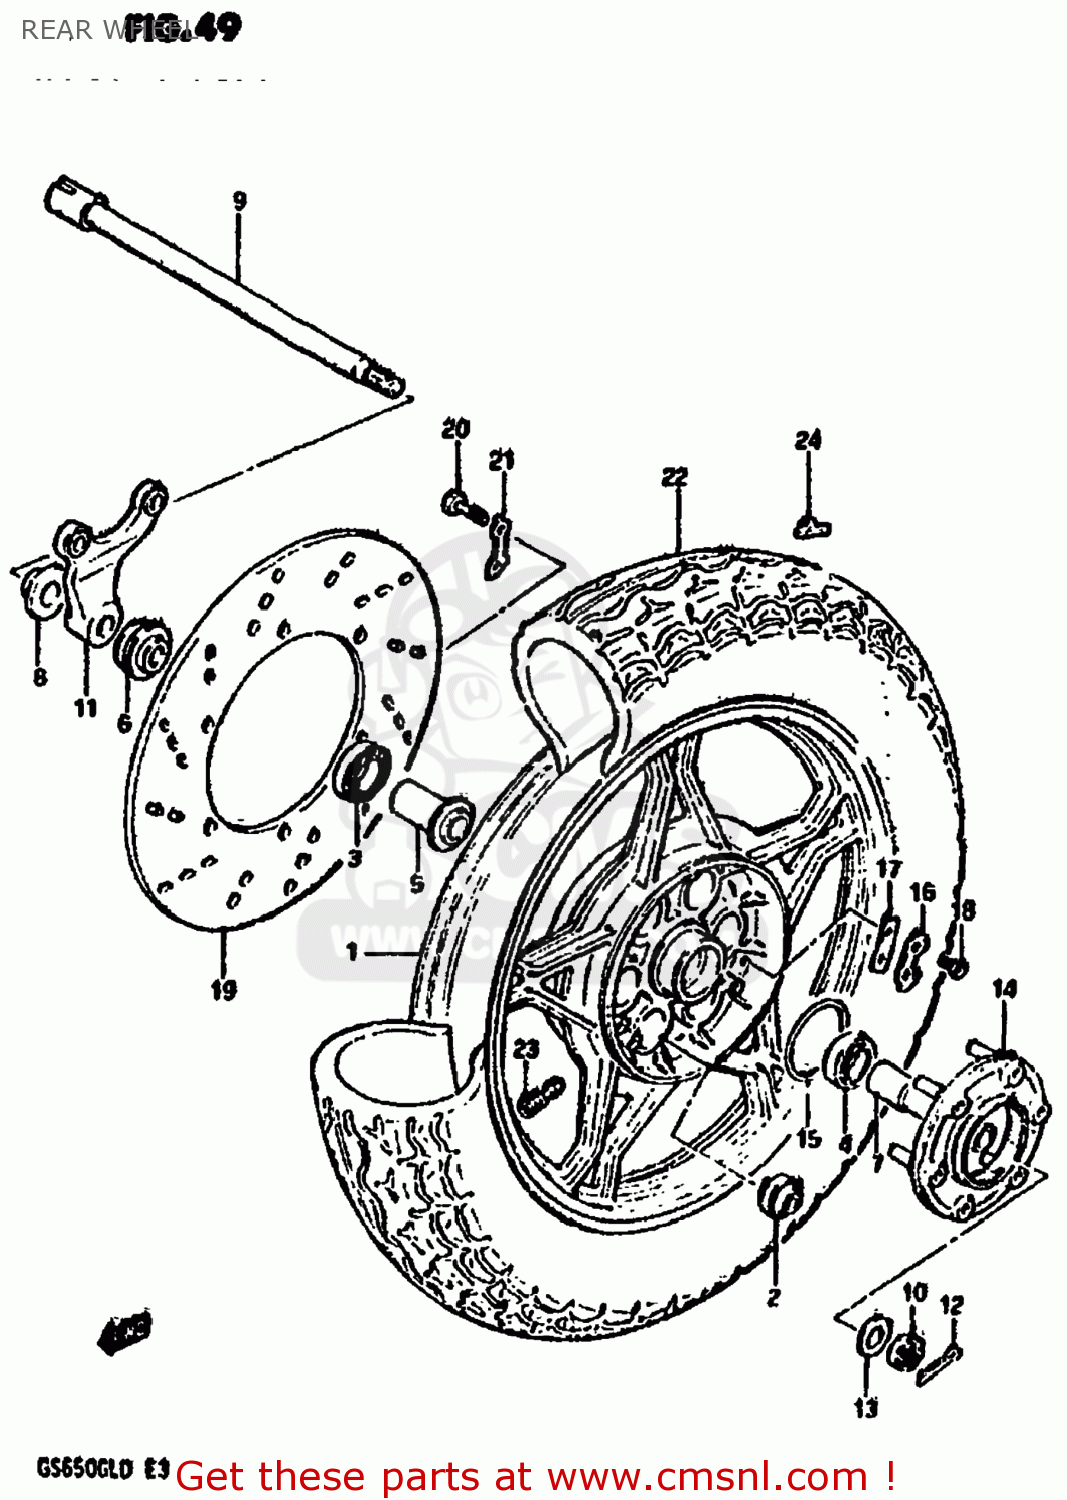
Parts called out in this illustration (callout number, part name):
1	CASTING WHEEL,REAR
2	BUSH
3	BEARING
4	BEARING
5	SPACER,REAR HUB BEARING
6	SPACER,REAR AXLE
7	SPACER,REAR AXLE,LEFT
8	SPACER,REAR AXLE,RIGHT
9	AXLE,REAR
10	NUT
11	BRACKET,RR,CALIPER
12	PIN,COTTER
13	WASHER(16.5X36X3.2)
14	JOINT ASSEMBLY,REAR HUB DRUM
15	O RING(D:2.1,ID:65)
16	WASHER
17	WASHER,THRUST(T:1.6)
18	BOLT(6X16)
19	DISC,RR BRAKE
20	BOLT(8X25)
21	WASHER
22	TIRE
23	TIRE
24	BALANCER,WHEEL
